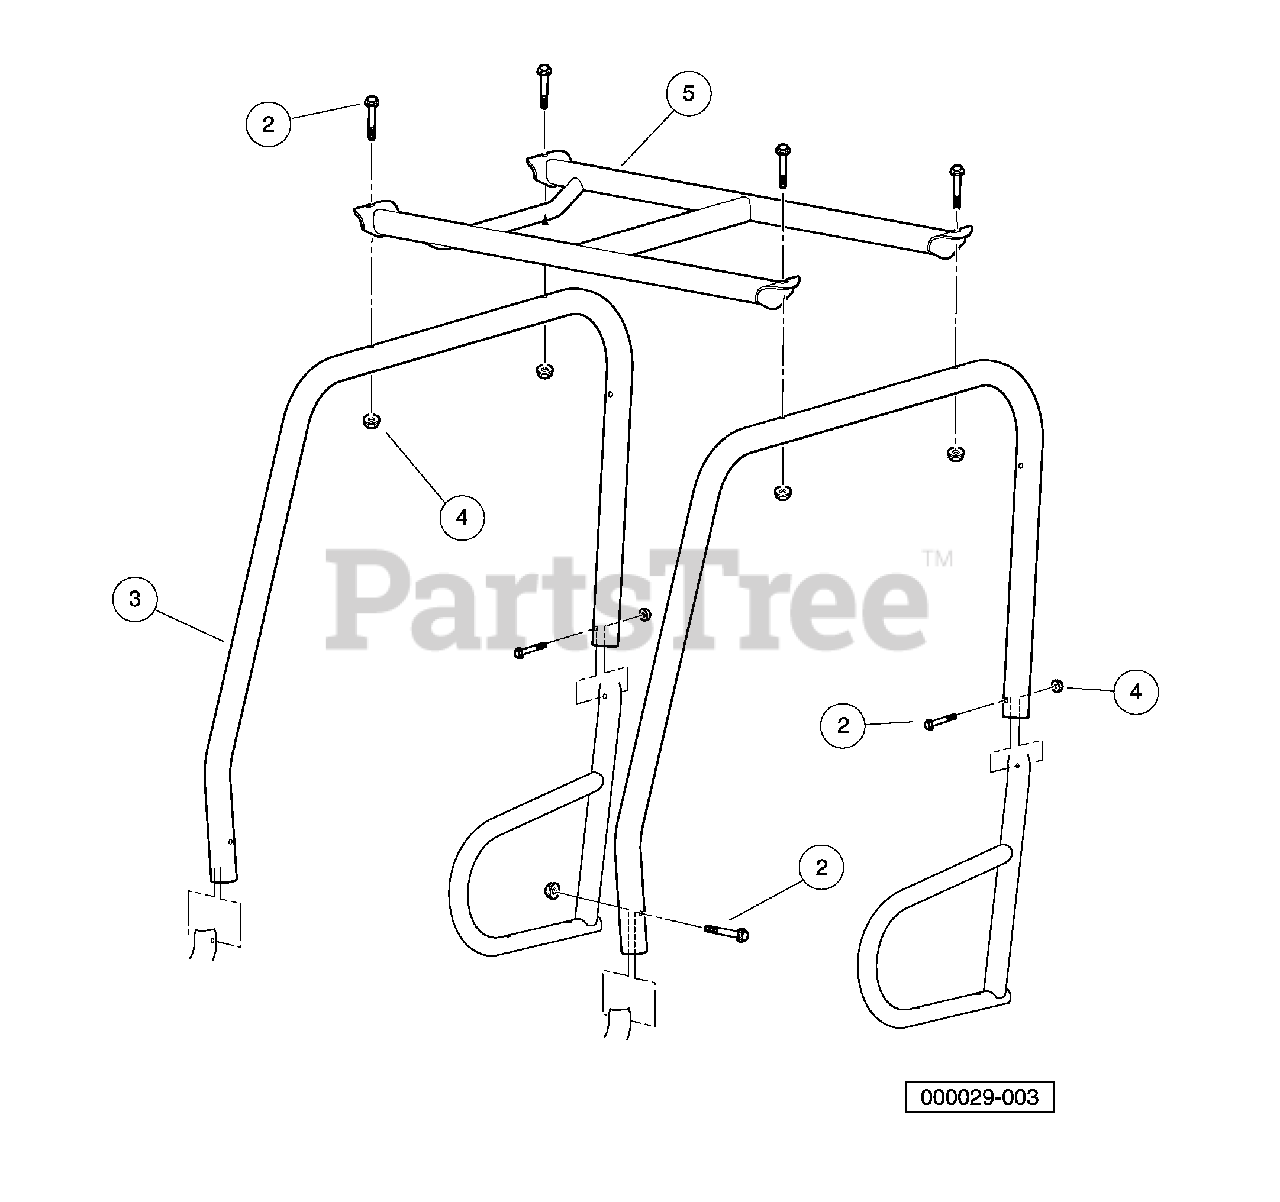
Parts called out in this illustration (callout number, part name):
1	Kit, ROPS, Domestic
2	Bolt, Flanged, M10 X 1.5 X 65
3	Tube, Side Support Short, ROPS
4	Nut, Flanged, M10 x 1.5, Black
5	Asm, Top, ROPS
